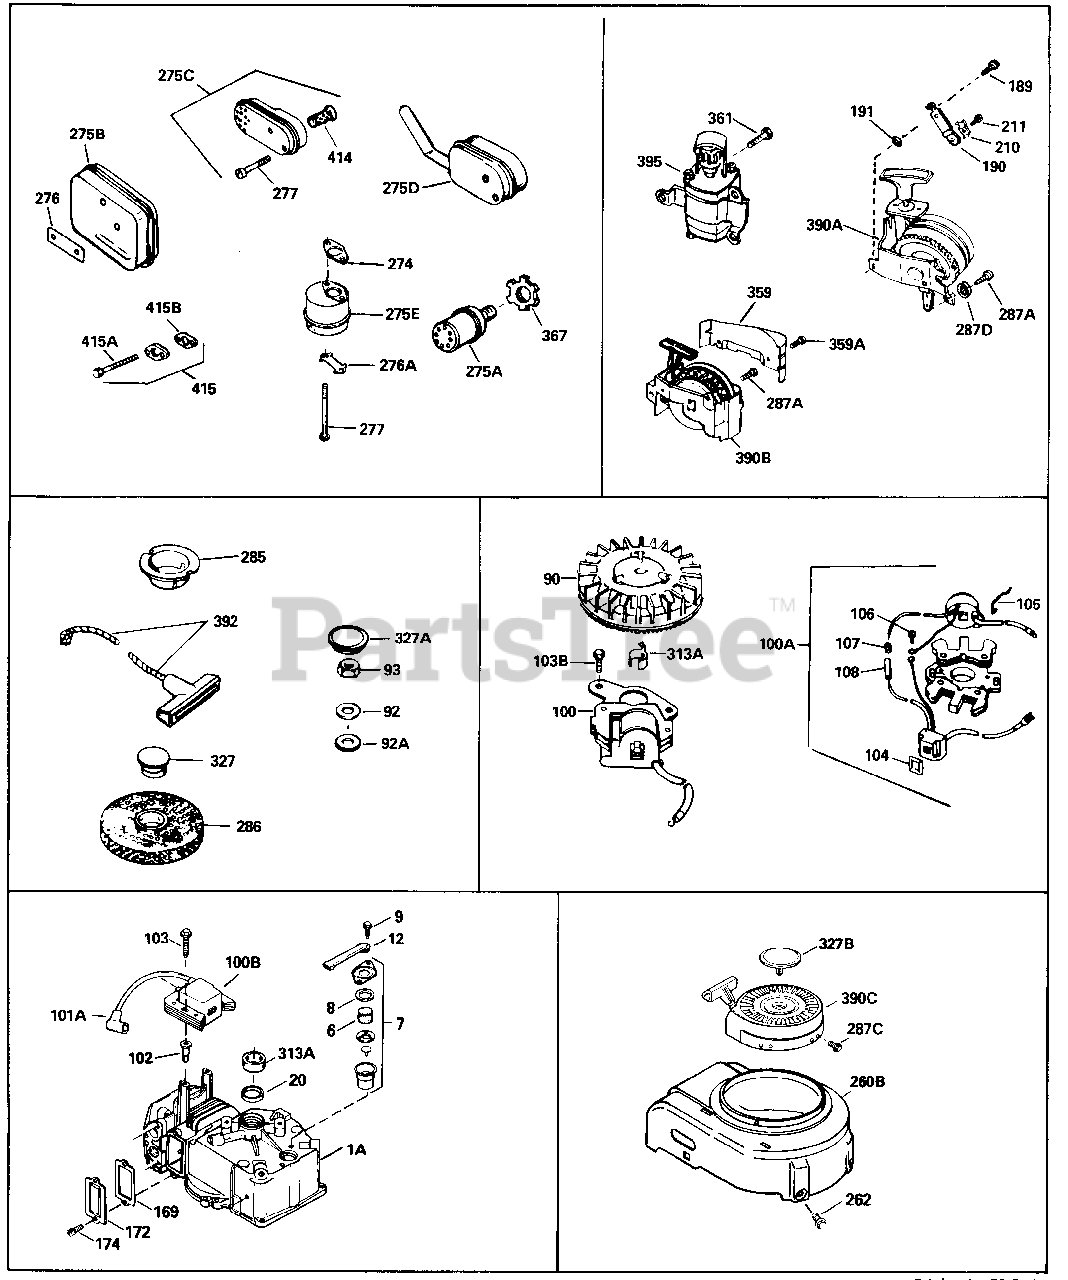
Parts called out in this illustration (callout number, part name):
20	Oil Seal
92	Washer Belleville
93	Nut, Flywheel
101A	Cover, Spark plug
174	Screw, 10-24 x 1/2"
277	Screw, 1/4-20 x 2-1/4"
285	Cup, Starter
415	Exh.Adapter Kit (Incl. 415A & B) use as req.
415A	Screw, T-30, 1/4-20 x 1/2"
415B	Intake Pipe Gasket
